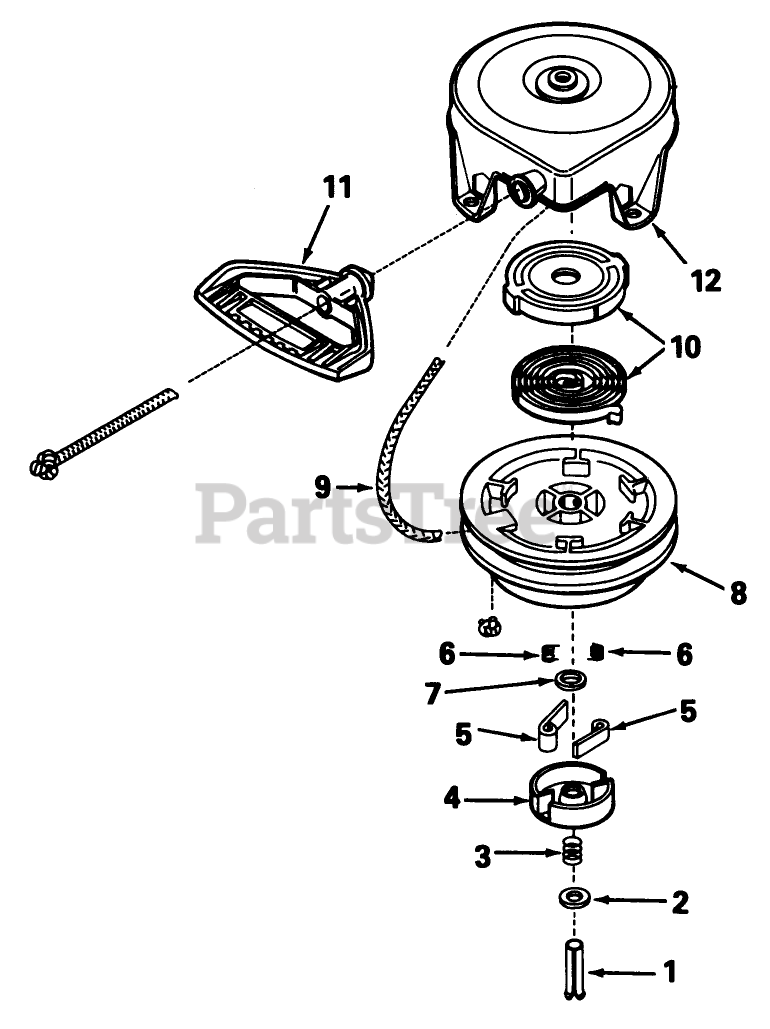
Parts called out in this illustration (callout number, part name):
1	Pin, Spring (Incl. Ref. #7)
2	Washer
3	Brake Spring
4	Retainer
5	Dog-Starter
6	Spring-Dog
7	Washer
8	Pulley
9	Rope-Starter
10	Spring Keeper Assy.
11	Handle-Starter, Mitten Grip
12	Housing Assy., Starter
